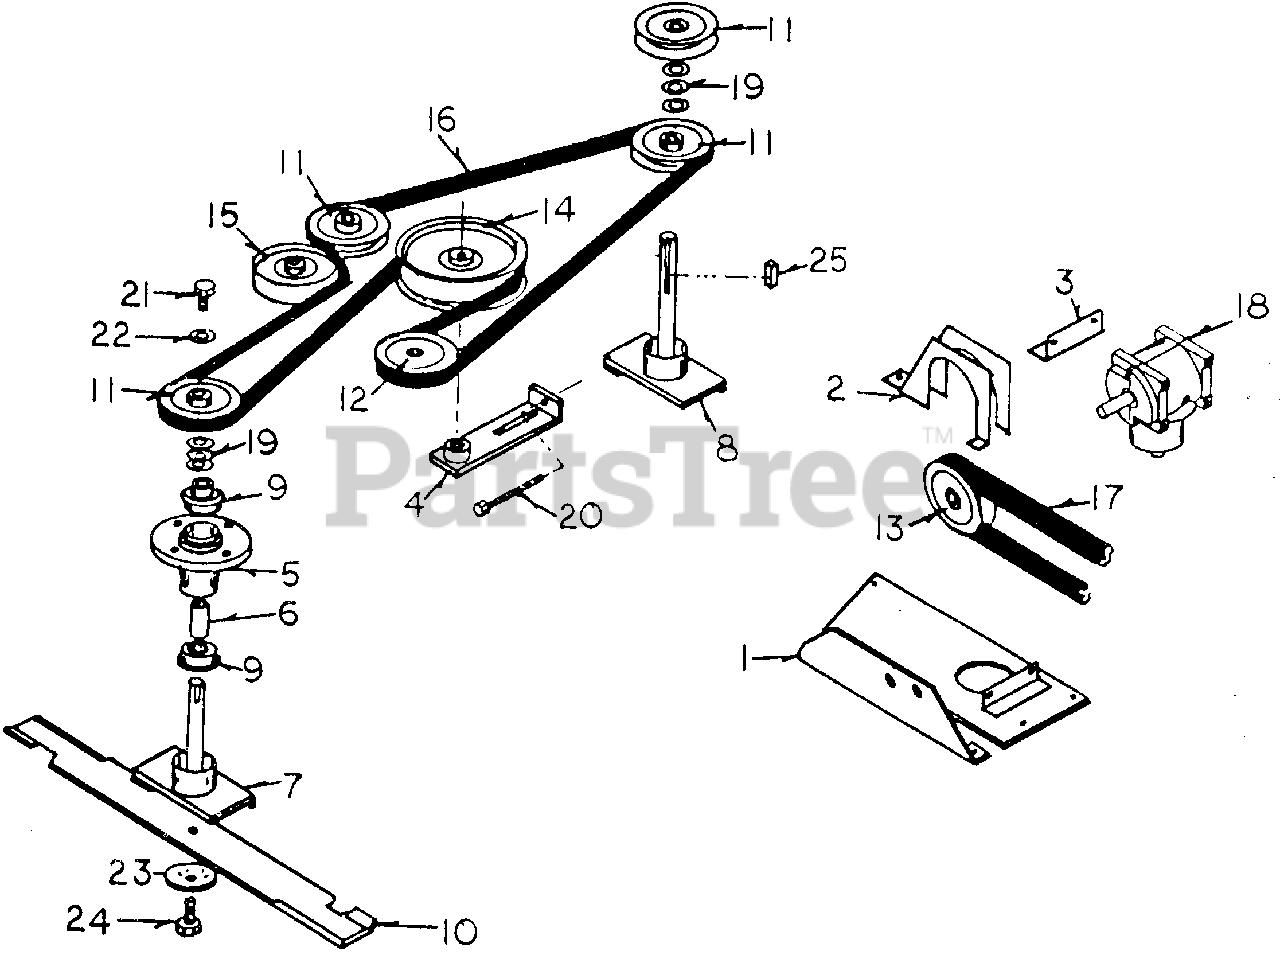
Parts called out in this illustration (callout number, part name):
2	Belt Guard
3	Gearbox Mount Angle
4	Belt Tightener
5	Spindle Housing
6	Spindle Spacer
7	Spindle Shaft
8	Spindle Shaft, Long
9	Spindle Bearing
11	Spindle Pulley
12	Gearbox Pulley, Out Put
13	Gearbox Pulley, In Put
14	Idler Pulley, Large
15	Idler Pulley, Small
17	Deck Drive Belt
20	Adjustment Bolt
21	Hex Bolt, 5/16-24 x 3/4"
22	Washer, 5/16", 10 Ga.
24	Hex Bolt, 3/8-24 x 1 1/14
25	Key Stock, 3/16
